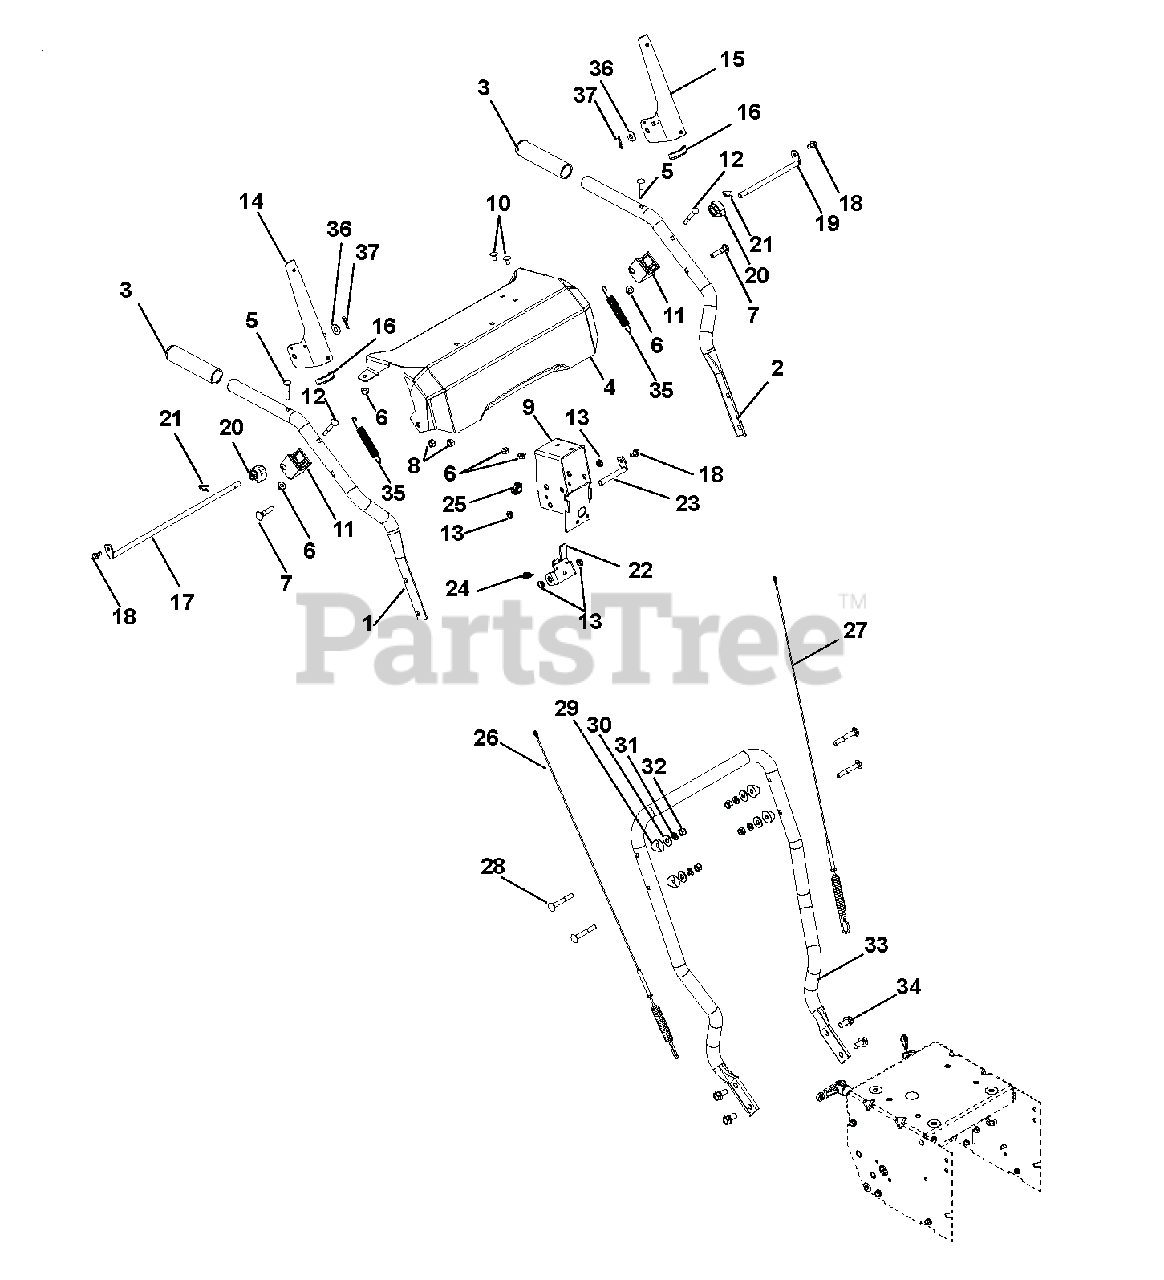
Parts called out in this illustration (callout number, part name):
1	HANDLEBAR, UPPER - RH
2	HANDLEBAR, UPPER - LH
3	HANDLE GRIP
4	CONTROL PANEL W/DECAL SNO-TEK
5	BLT-RDHDXLSQNK.25-20X1.25 G5ZC
6	@NUT-LK-TOP-FLG .25-20 YWZC
7	BLT-RDHDXLSQNK .31-18X2.0 G5YZ
8	@NUT-LK-CTR .31-18 YWZC
9	WELDMENT, BRACKET INTERLOCK
10	@BLT-RDHDSQNK .25-20X.50 G5YZ
11	BLOCK, CLUTCH PADDLE
12	BLT-RDHDXLSQNK .25-20X2.0 G5YZ
13	BUSHING, POLYLINER-.38 SNAPIN
14	LEVER, CLUTCH-RH
15	LEVER, CLUTCH-LH
16	EDGING, CLUTCH PADDLE - 2.00"
17	ROD, PADDLE MOUNT - LONG
18	SCR-TAP .25-20X.50 HWH TR YWZ
19	ROD, PADDLE MOUNT - SHORT
20	CAM, INTERLOCK
21	PIN, SPRING CLIP
22	BRACKET, INTERLOCK ARM
23	ROD, PIVOT - INTERLOCK
24	SPRING-EXT .047X.438X1.45
25	CRANK BUSHING, NYLON CHUTE BK
26	CABLE, AUGER (SINGLE SPEED)
27	CABLE, UPPER TRACTION (SS)
28	@BLT-RDHDSQNK .31-18X2.25 G5YZ
29	SPACER, HANDLEBAR
30	@WSHR-FL-STL.38X.875X.083 YWZC
31	WSHR-LK .312X.097 HVY YWZC
32	@NUT-LK-NYL .312-18 YWZC
33	HANDLEBAR, LOWER 939 SERIES
34	BLT-SERHFWH .38-16X.75 YWZC
35	SPRING, EXTENSION
36	@WSHR-FL-STL.281X.62X.065 YWZC
37	PIN-HAIR INT .06X.18X.77
